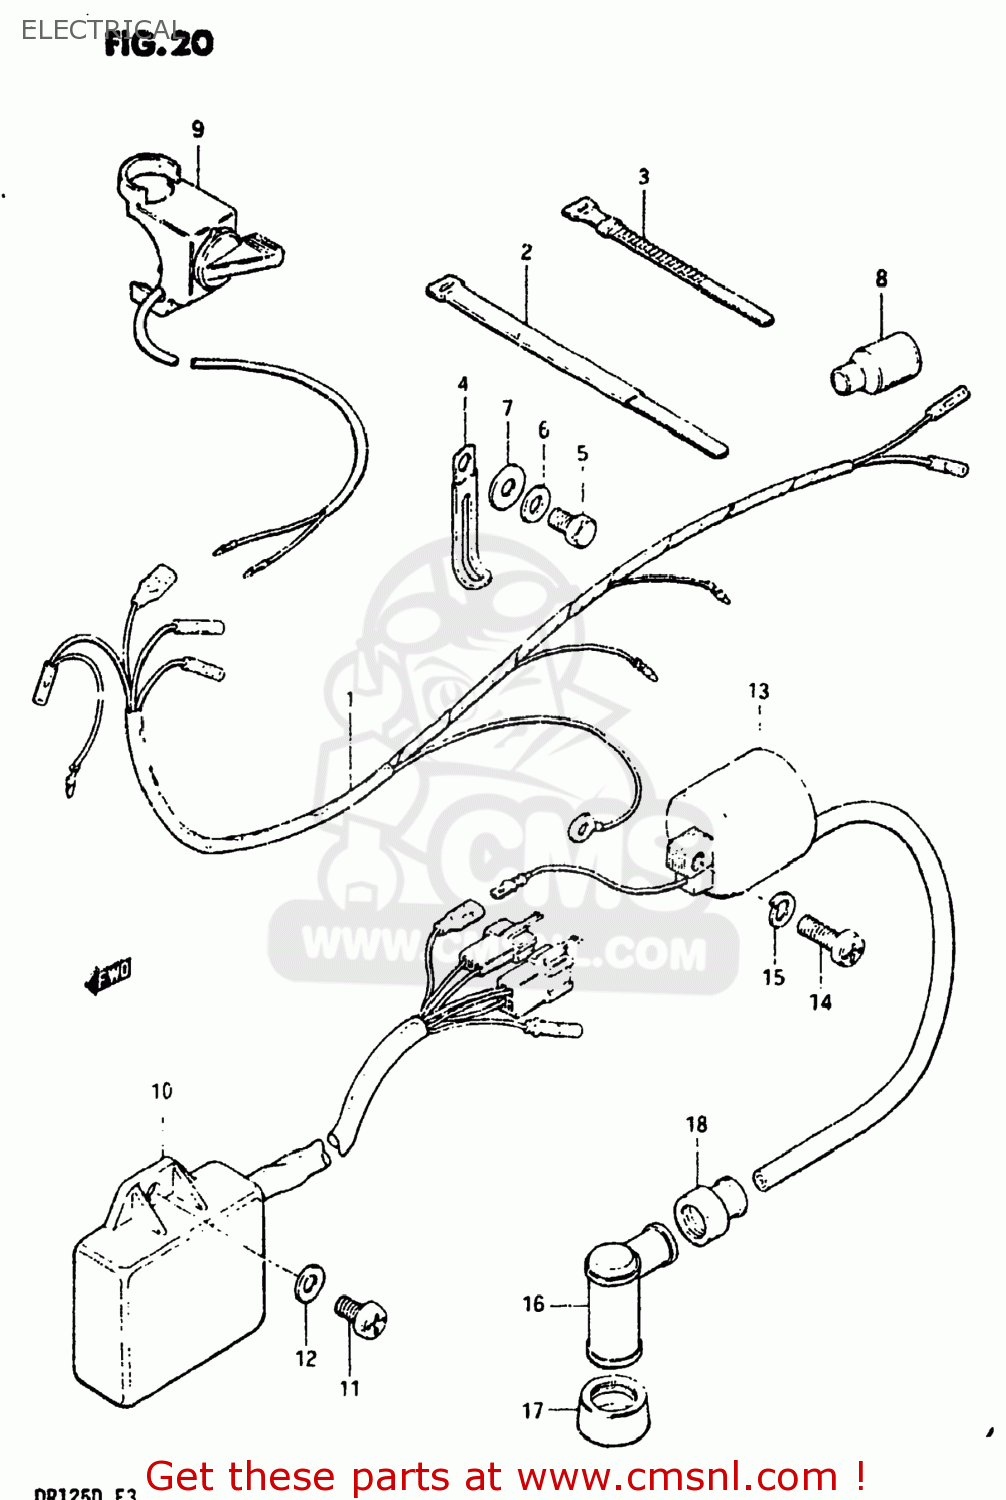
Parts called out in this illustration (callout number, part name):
1	HARNESS,WIRING
2	CLAMP
3	CLAMP(L:120)
4	CLAMP
5	BOLT, UPPER
6	WASHER
7	WASHER
8	BOOT,WIRING HARNESS
9	SWITCH ASSY,ENGINE STOP
10	CDI UNIT
11	SCREW
12	WASHER
13	COIL ASSEMBLY,IGNITION
14	SCREW
15	LOCK WASHER
16	CAP ASSY,SPARK PLUG
17	SEAL,SPARK PLUG
18	SEAL,SPARK PLU
